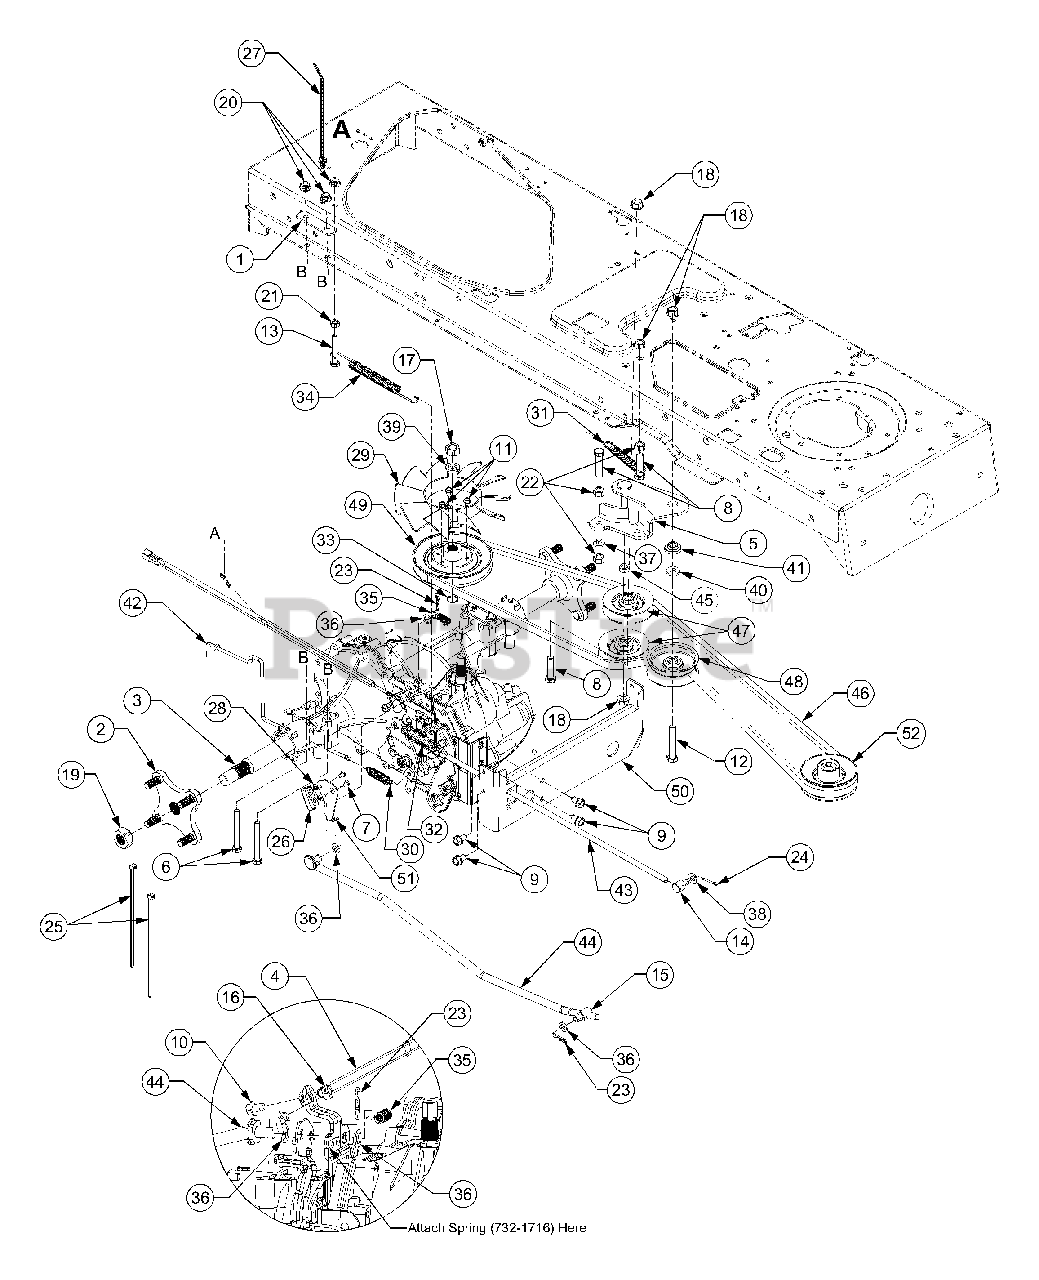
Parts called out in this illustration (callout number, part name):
2	Hub Assembly, Wheel
3	Transmission, Hydrostatic
4	Harness Assembly, Ground & Reverse
5	Bracket Assembly, Idler, Center Dbl
6	Hex Cap Screw, 5/16-18, 2.75, Gr5
7	Screw, #8-18, 0.500
8	Hex Cap Screw, 3/8-16, 1.50, Gr5
9	Screw, 5/16-12, 0.75
10	Screw, 1/4-20, 0.5
11	Screw, #12-24, 0.375
12	Hex Cap Screw, 3/8-16, 2.25, Gr5
13	Hex Cap Screw, 5/16-18, 2.00, Gr5
14	Ferrule, 5/16-18 x .312 Dia
15	Ferrule, 3/8-24 x .375 Dia
16	Nut, Hex Lock, 1/4-20
17	Nut, Hex, 1/2-20, Gr2
18	Nut, Flange Lock, 3/8-16
19	Nut, 3/4-16, Grb, Hx
20	Nut, Flange Lock, 5/16-18, Gr5
21	Nut, Hex, 5/16-18, Gr5
22	Nut, Hex, 3/8-16, Gr8
23	Pin, Cotter, .072 Dia. x 1.13 Lg
24	Pin, Cotter, 3/32, 1.0
25	Cable, Tie, 3/16 x .05 x 7.4
26	Switch, Spring, Short
27	Tie, Cable, Push Mount 7.5 Lg
28	Plate, Insulator Nut
29	Fan, Blade, 10"
30	Spring, .48 OD x 2.03 Extension
31	Spring, Extension, .50 Dia x 3.97 Lg
32	Spring, Extension, .59 OD x 4.00 Lg
33	Ring, Wire
34	Spring, Extension, .500 Dia x 7.0 Lg
35	Spring, Extension, 3/8 OD x 1.44 Lg
36	Washer, Flat, .385 x .62 x .063
37	Washer, Lock, 3/8 , Regular Duty
38	Washer, Flat, .344 x .688 x .065
39	Washer, Lock, 1/2 , Regular Duty
40	Washer, Flat, .407 x .812 x .135 Hdn
41	Spacer, Shoulder, 1.00 x .38 x .38
42	Rod, Hydro Bypass
43	Rod, Brake, Hydro
44	Rod, Control, Hydro
45	Spacer, .376 ID x .625 OD x .22
46	Belt, V Type, Poly
47	Pulley, Idler, V Type x 3.06 Dia
48	Pulley, Idler, Flat 2.75 OD
49	Pulley, Input, 5.0 Dia
52	Pulley, Engine, 3.56 Dia.
